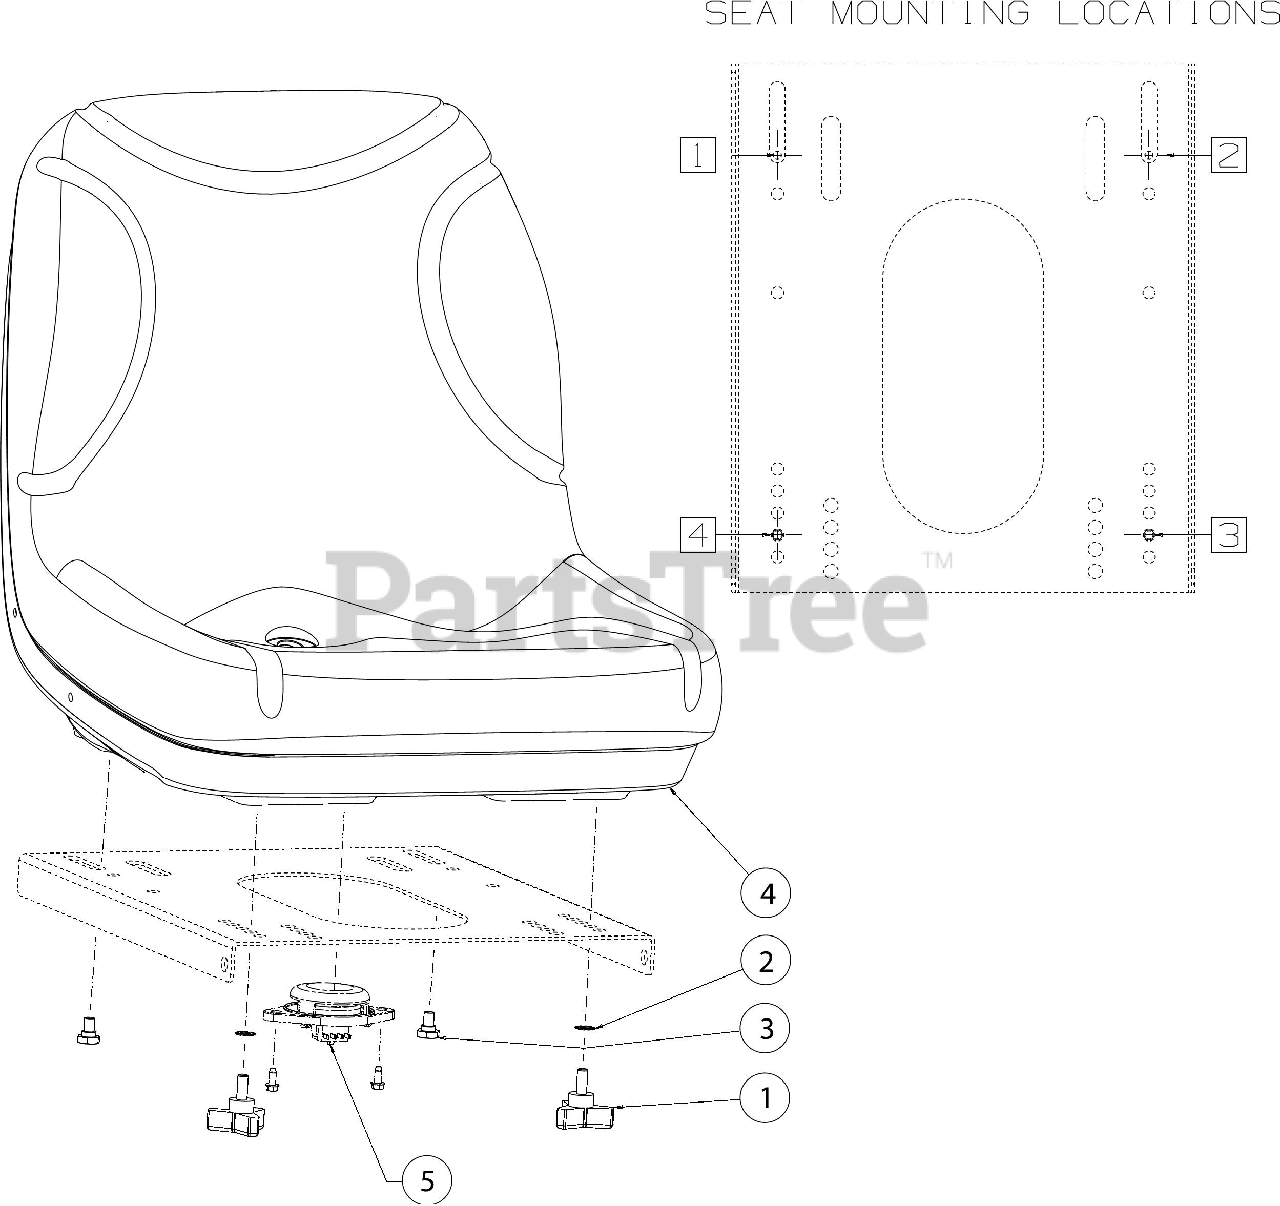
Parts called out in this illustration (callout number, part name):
1	THREE ARM KNOB
2	WASHER
3	SHOULDER SCREW .437
4	19" SEAT 4-PT MOUNT
